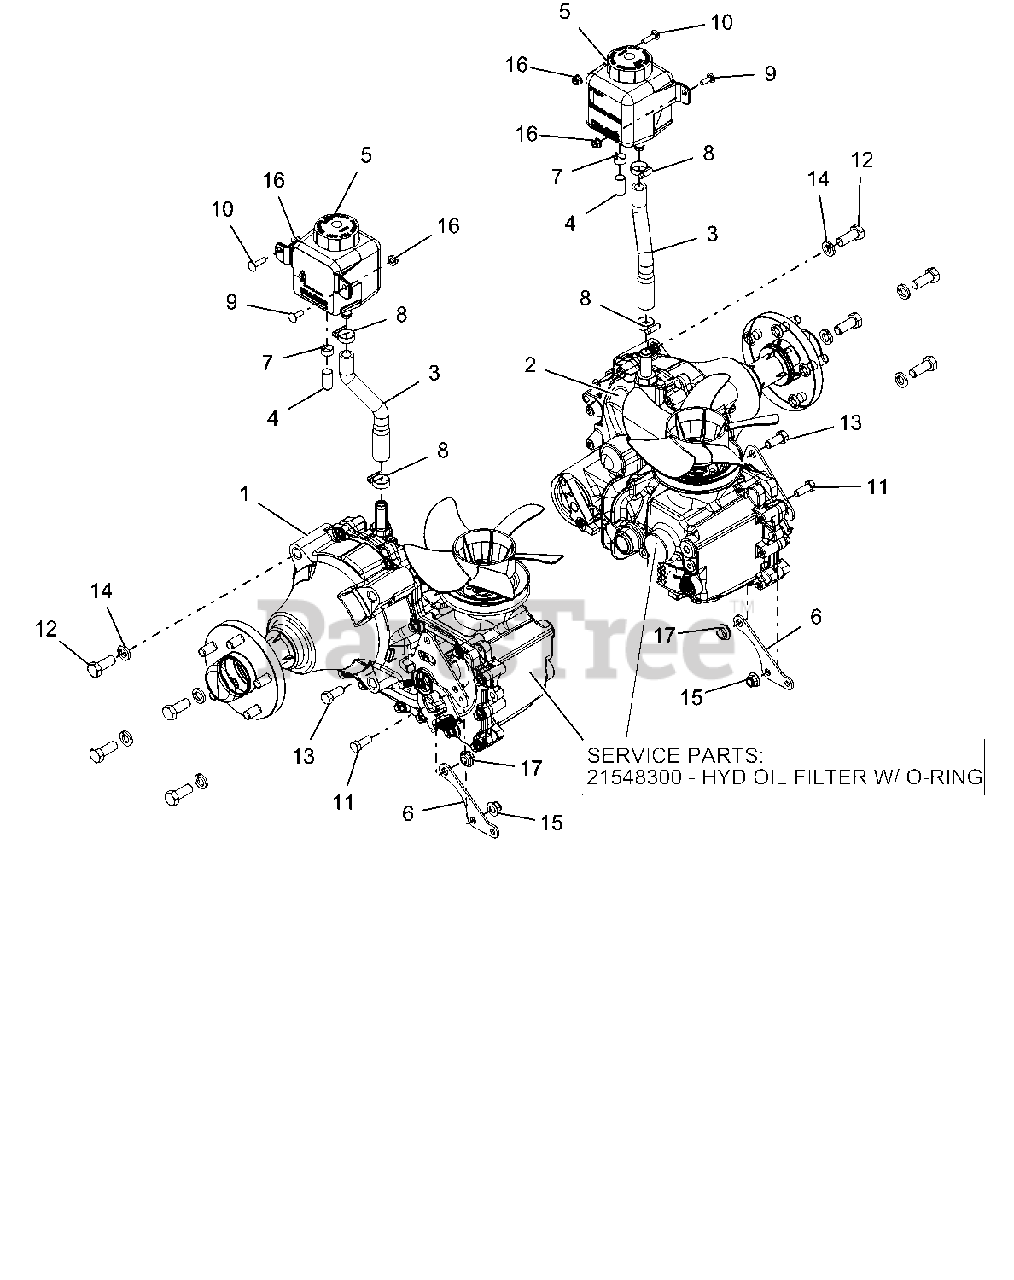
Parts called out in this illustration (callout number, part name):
1	TRANS, R.H. HG ZT-5400
2	TRANS, LH HG ZT-5400
2	HYD OIL FILTER W/ O-RING
3	HOSE, PT200/400 TRANSAXLE OVERFLOW
4	CAP, .50 BARBED FITTING
5	TANK, HYDRO OVERFLOW 700ML
6	BRKT, DRIVE CONTROL LINKAGE MTG
7	CLAMP, HOSE
8	CLAMP, .88 DIA HOSE
9	BLT-RDHDSQNK .25-20X.75 G5 YWZC
10	BLT-RDHDSQNK .25-20X1.00 G5 YWZC
11	BLT-HEX .38-16X1.00 GR5 YWZC
12	BLT-HEX .50-13X1.25 GR5 YWZC
13	BLT-HEX .44-14X1.00 GR5 YWZC
14	WSHR-LK .50X.125 REG YWZC
15	NUT-LK-NYL-FLG .38-16 YWZC
16	NUT-LK-NYL-FLG .25-20 YWZC
17	NUT-LK-NYL-FLG .44-14 YWZC
